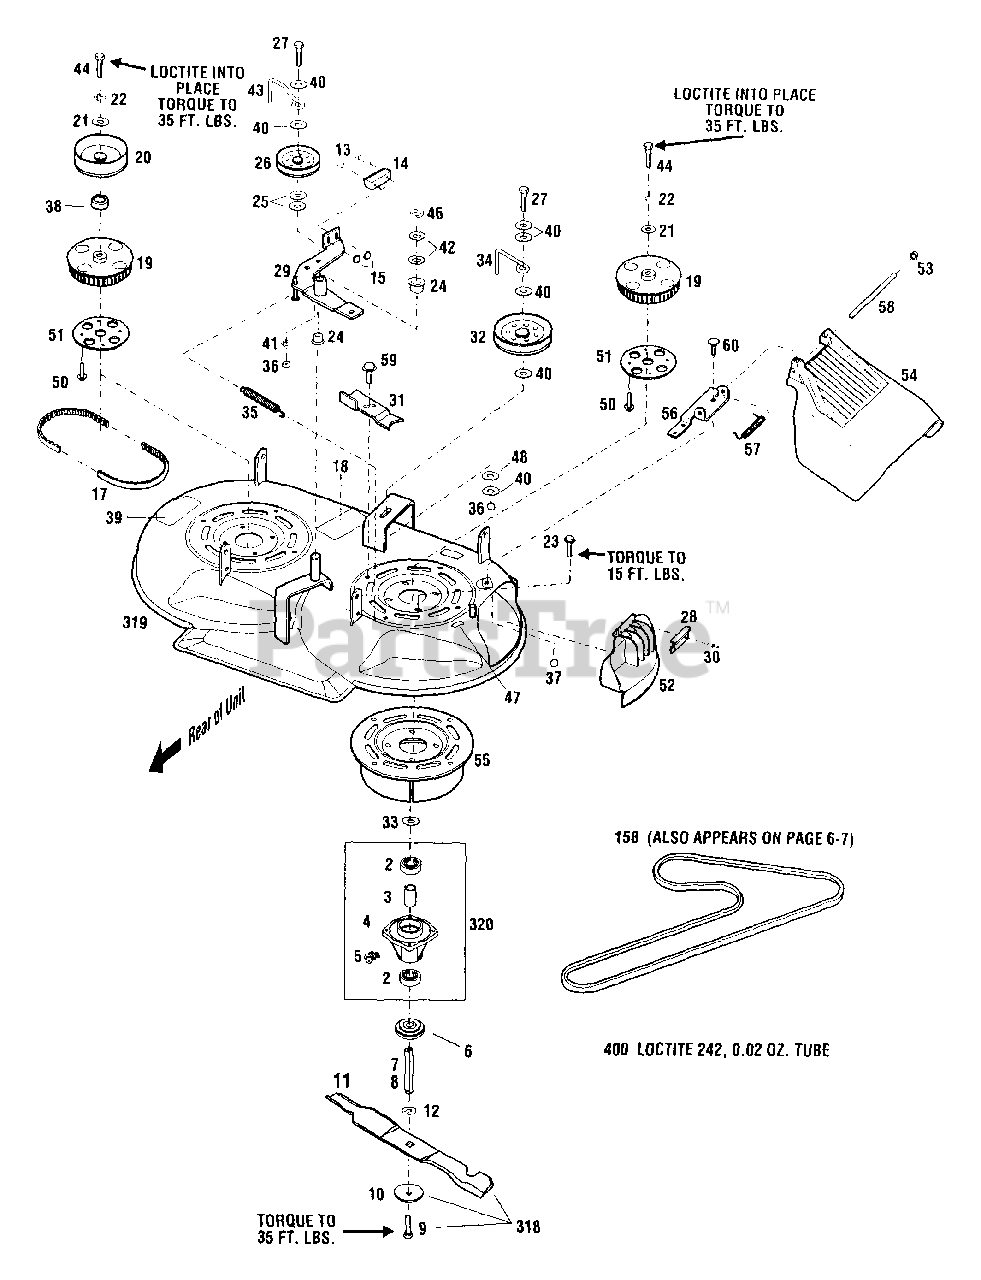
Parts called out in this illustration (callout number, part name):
2	Ball Bearing
3	Spacer
4	Mower Spindle
5	Grease Fitting
6	Blade Spacer
7	Right Spindle Shaft
8	Left Spindle Shaft (long)
9	Screw, 7/16-14 x 1
10	Belleville Washer
11	Blade, 33" Mulching
12	Retaining Ring
13	Flat Head Screw, #10-24 x 1-1/4
14	Brake Pad
15	Nylon Locknut, #10-24
17	Toothed Drive Belt
18	Caution Decal
19	Cogged Pulley, 56T
20	Drive Pulley
21	Flat Washer, 7/16
22	Lock Washer, 7/16
23	Flange Lock Screw, 5/16-18 x 1
24	Flange Bushing
25	Flat Washer
26	Idler Pulley
27	Hex Head Capscrew, 3/8-16 x 2-1/2
28	Adapter Trim
29	Idler Arm
30	Pop Rivet
31	Belt Tension Adjustment Bracket
32	Idler Pulley
33	Special Thrust Washer
34	Belt Guide
35	Extension Spring
36	Nut, 3/8-16
37	Locknut, 5/16-18
38	Pulley Spacer
39	Danger Decal
40	Flat Washer, 3/8 x 3/4
41	Lock Washer, 3/8
42	Flat Washer
43	Belt Guide
44	Screw, 7/16-14 x 1-1/4
46	Retaining Ring
47	Warning Decal
48	Pyramid Washer, 3/8
50	Triplask Screw, 1/4-20 x 5/8
51	Sprocket Plate
52	Mulcher Cover, Fold-Up Style
54	Discharge Chute
55	Weldment Doubler
56	Bracket, Chute Hinge
57	Spring, Discharge Chute
58	Pin, Discharge Chute
59	Screw, Thread-Forming
60	Bolt, Carriage, 3/8-18 x 3/4
158	V-Belt
318	Mulching Blade Kit
319	Mower Deck Assembly
320	Mower Spindle Assembly
400	Loctite 242, 0.02 oz. Tube
